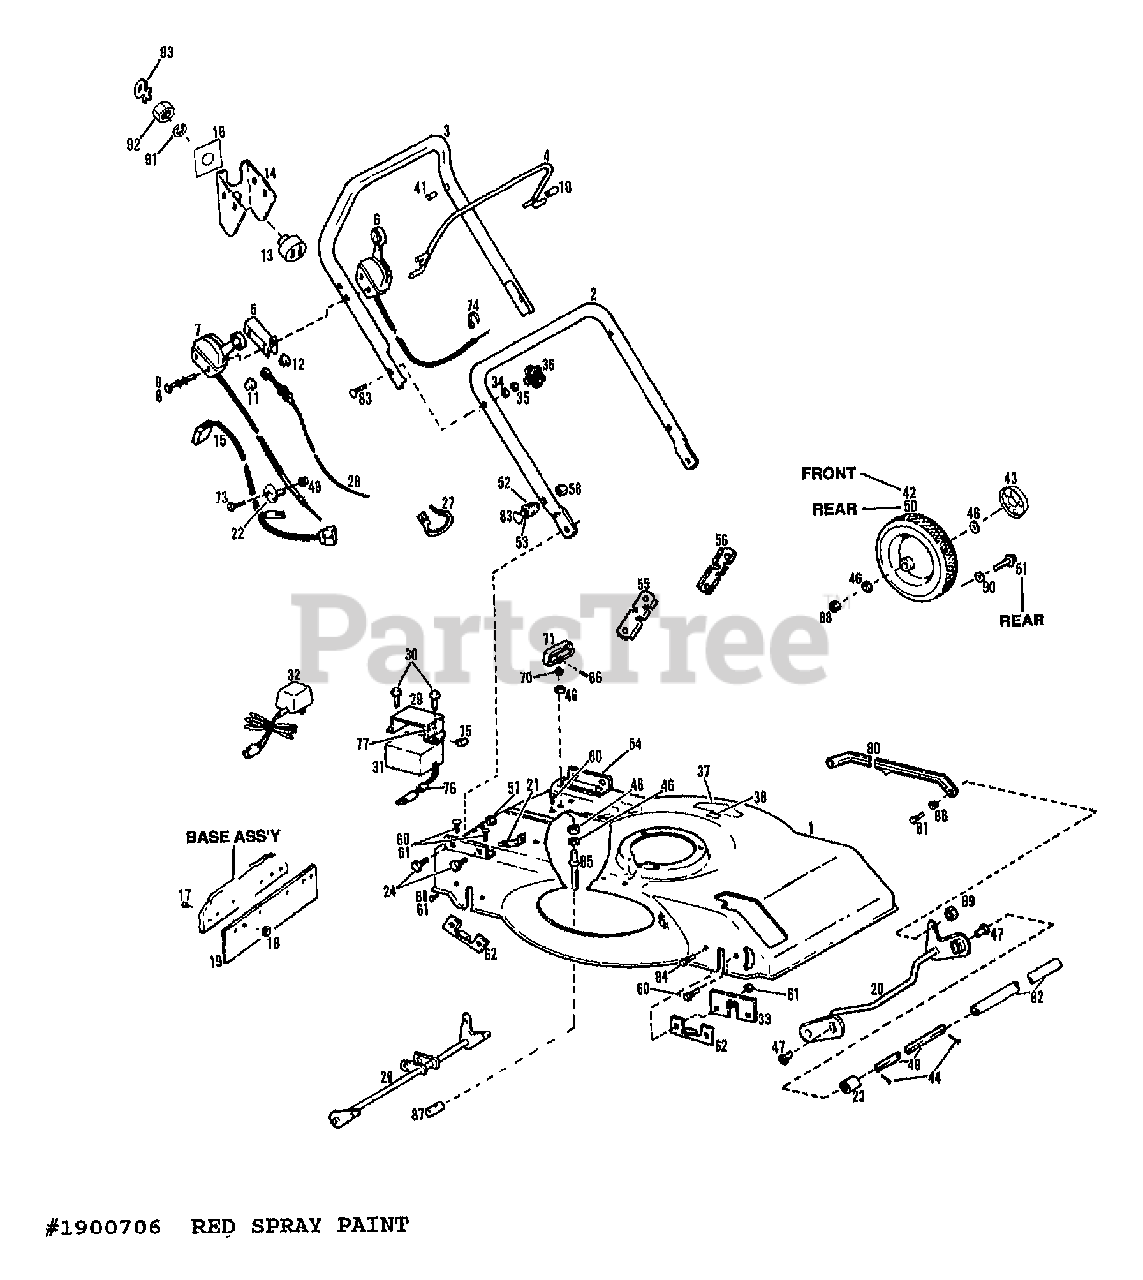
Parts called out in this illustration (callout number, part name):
1	ASSM-BASE W/DECAL 22"MLCH
2	HANDLE-LOWER
3	HANDLE-UPPER
4	ASSM-BAIL ENGINE CONTROL
5	SUPPORT-CONTROL
6	CONTROL-THROTTLE
7	CLUTCH-CONTROL
8	SCR-HH SEMS
8	SCR-HHS {8656}
9	NUT W/LKWASHER 10-24 ZP
10	GRIP-HANDLE
11	CAP-PUSH ON .312 DIA
12	RING-GRIP EXT .312 ID
13	SWITCH-EL IGNITION {8656R}
14	SUPPORT-SWITCH {8656R}
15	HARNESS-WIRE {8656R}
16	DECAL-ELEC START
17	RIVET-POP
18	WASHER-.88X.2X.059
19	SHIELD-DEFLECTOR
20	FRONT AXLE ASSEMBLY
20	KIT-AXLE ASM FRNT
20	ASSM-FRONT AXLE
21	CLUTCH CABLE BRACKET
22	CLAMP-POWDEN WIRE
23	BUSHING-AXLE
24	SCR-HH 3/8-16X.75 G5 ZP
26	ASSM-AXLE REAR
27	TIE-CABLE
28	CABLE-ENGINE BRAKE
29	CLAMP-BATTERY {8656R}
30	SCR-FLANGE 1/4-20X3/4 GR5
31	KIT-BATTERY REPLACE {8656R}
32	CHARGER-ELEC BATTERY {8656R}
33	PLATE-DOUBLER
34	WASHER-LK .312 ZP
35	WASHER-FLAT 5/16 SAE
37	DECAL-OPEI CAUTION {8656R}
38	DECAL-INDICATOR
41	BEARING-FLANGED
42	TIRE/WHEEL FRONT F/TB MULCH MW
43	CAP-HUB T/B MULCHERS
44	PIN-COTTER .125 X .75 ZP
46	WASHER-FLAT .88X.5X.06 ZP
47	BEARING-AXLE
48	AXLE-DRIVE
49	NUT-HFLK 10-24
50	ASSM-TIRE & WHEEL
51	SCR-SHLDR 3/8-16
52	SPRING-COMPRESSION
53	SPACER
54	BRKT-HANDLEBAR
55	SUPPORT-HANDLE RH
56	SUPPORT-HANDLE LH
57	NUT-LOCK 3/8-16
58	NUT-HFT/LK
60	SCR-CARR 5/16-18X.62 G2 ZP
61	NUT-HFLK 5/16-18 ZP
62	BRACKET-AXLE
66	PIN-ROLL .188X1.0
70	SPACER-HANDLE
71	HANDLE-HEIGHT ADJ
73	SCR-HW M10-24X.88 EXTTOOTH
74	TIE-CABLE NYLON BLACK
75	CLAMP-WIRE {8656R}
76	DECAL-CHARGING INST {8656R}
77	PAD-BATTERY {8656R}
80	LINK-HEIGHT ADJUST
81	SCR-SHOULDER
82	TUBING-PLASTIC
83	SCR-CURVED HD 5/16-18X2.0
84	SCR-TRUSS HD 5/16-18X.62
86	BEARING-NYLINER
87	PIVOT-ADJUSTING SCR
88	NUT-HFLK 3/8-16 ZP
89	NUT, HEX JAM 5/16-18
89	NUT-HEX JAM 5/16-18
90	WASHER-1.12X.378X.125
91	WASHER-LK .625 INT TOOTH
92	NUT (IGNIT SWITCH)
93	KEY-IGNITION
